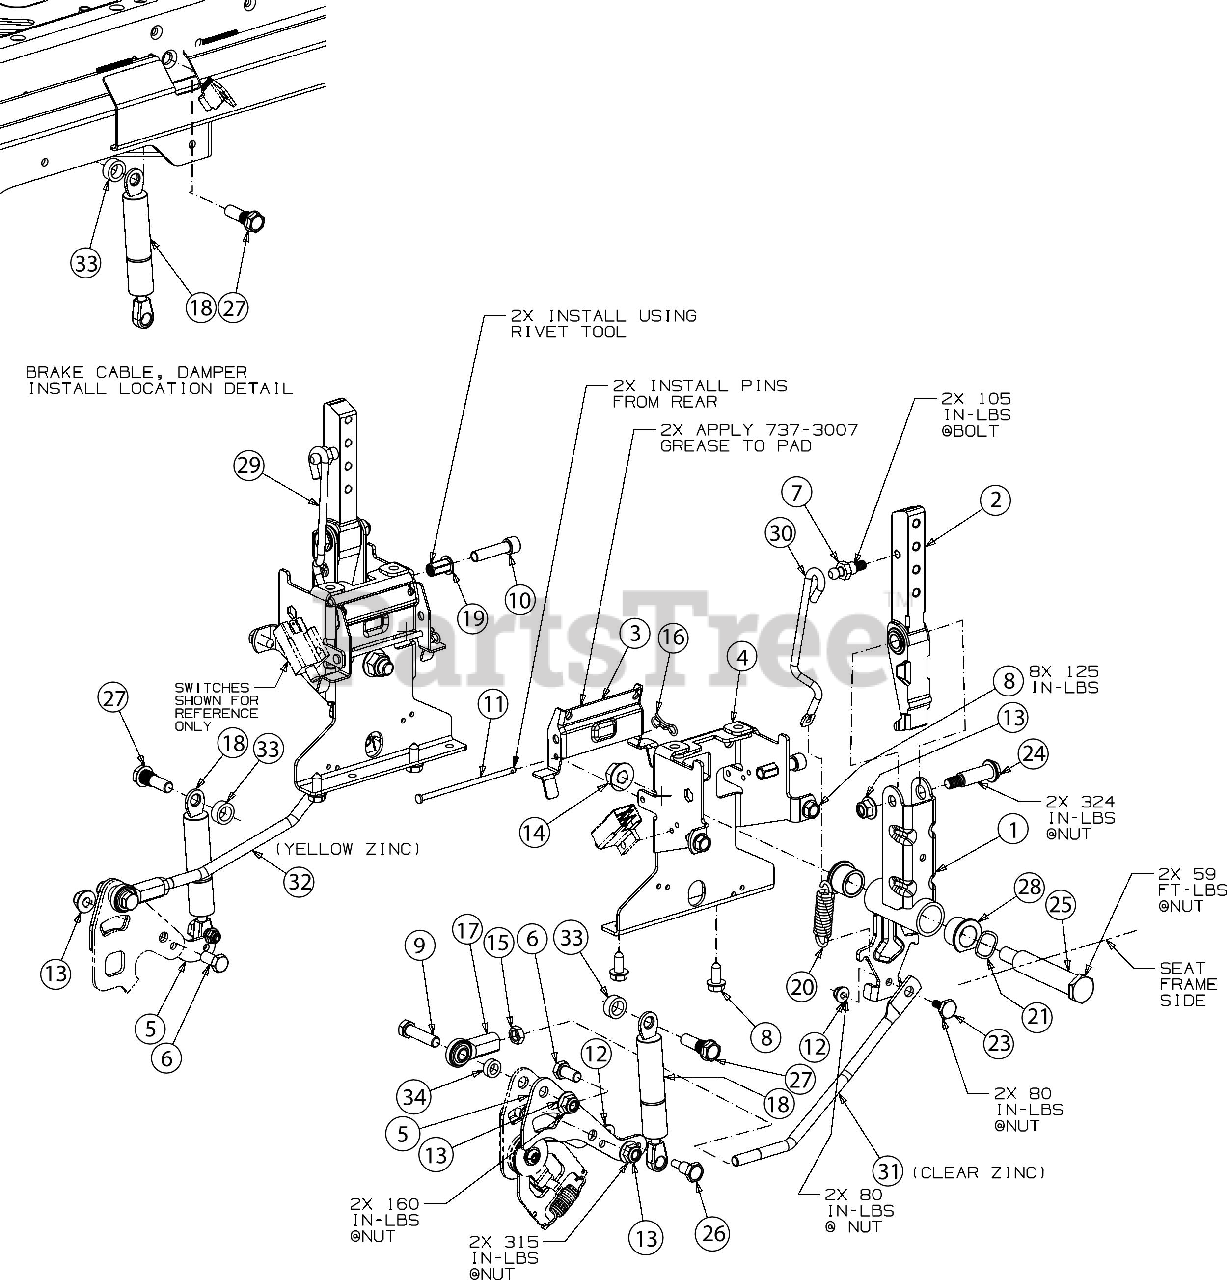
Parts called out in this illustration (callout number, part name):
2	LOWER ARM ASSEMBLY
6	HEX SCREW 3/8-16 x .75
7	SCREW 5/16-18 x .48
8	SCREW 5/16-18 x .750
9	SCREW 3/8-16 x 1.50
10	SCREW 3/8-16 x 1.50
11	PIN .188 x 4.1
12	FLANGE LOCK NUT
15	HEX JAM NUT 3/8X24
16	BOW TIE COTTER PIN 1/4-5/16
17	BALL JOINT (RH)
18	HYD DAMPER CYLINDER
19	NUT RIVET
20	EXTENSION SPRING
21	WAVE WASHER .785X1.00X.012
23	SHOULDER SCREW
24	SHOULDER BOLT .498 DIA x 1.296 LG
25	SHOULDER BOLT .750 DIA x 3.25 LG
26	SHOULDER BOLT .395 DIA x .56 LG
27	SHOULDER BOLT .395 DIA X.83 LG DOG
28	FLANGE BEARING
29	LAPBAR DETENT ROD (LH)
30	LAPBAR DETENT ROD (RH)
31	HYDRO CONTROL ROD (RH)
32	HYDRO CONTROL ROD (LH)
34	SPACER-.380 ID X.625 OD x .227
